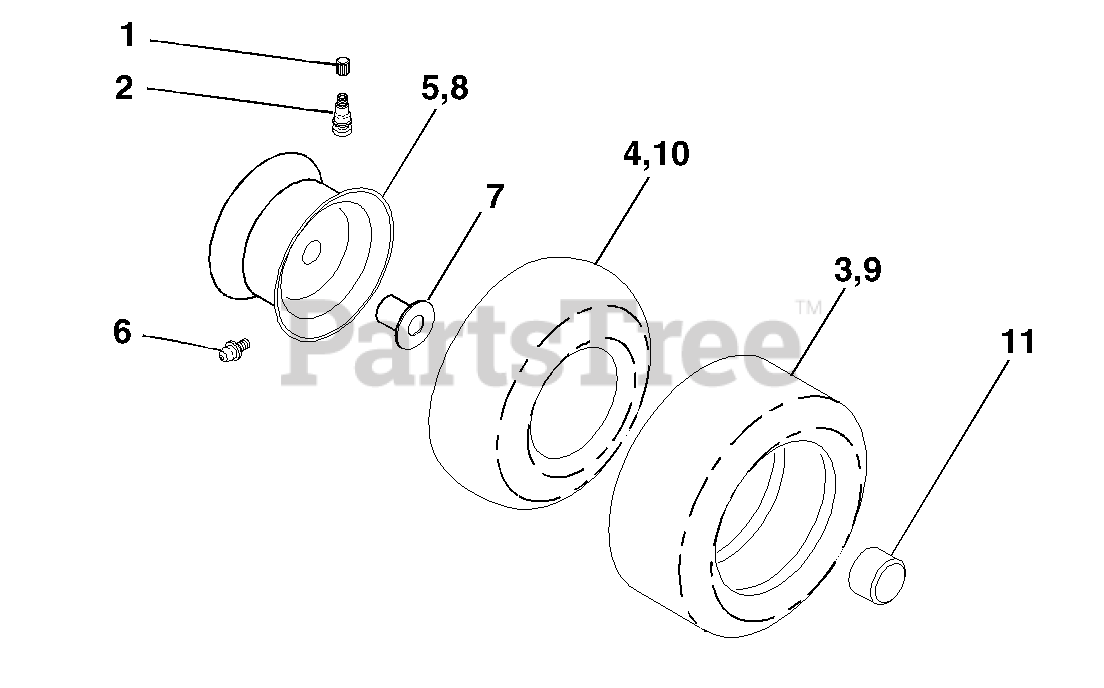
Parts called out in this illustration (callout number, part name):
1	Cap Valve Tire
2	Stem Valve
3	Tire F Ts 15 X 6 0 - 6 Service
4	Tube Front
5	Rim Asm 6"front Silver Service
6	Fitting Grease
7	Bearing Flange
8	Rim Asm 8"rear Silver Service
9	Tire R Ts 20x10-8 C Service
10	Tube Rear
11	Cap Axle Blk 1 50 X 1 00
